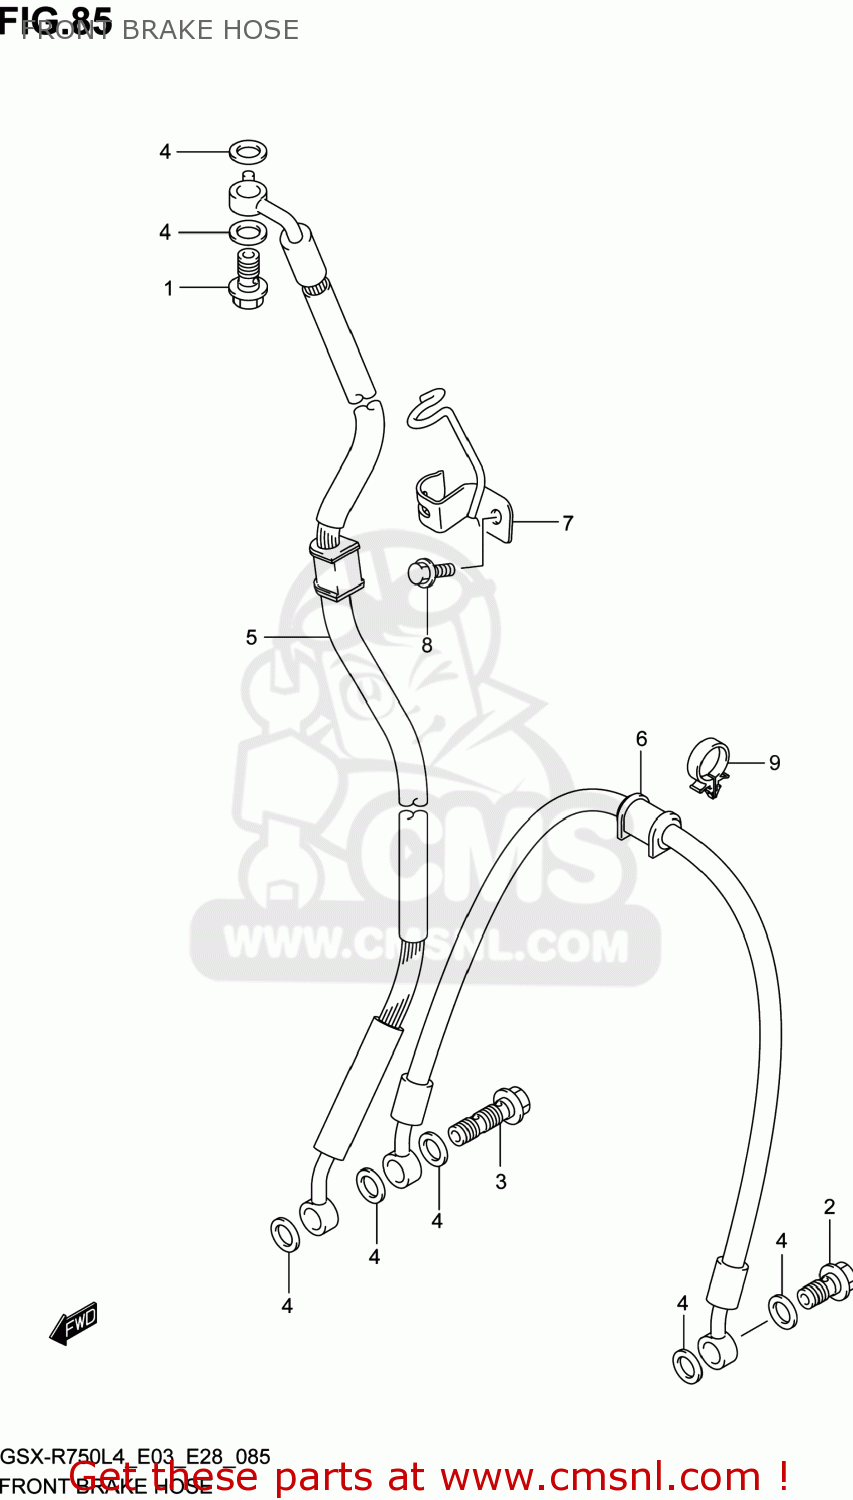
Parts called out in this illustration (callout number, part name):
1	BOLT UNION
2	BOLT UNION
3	BOLT UNION
4	WASHER(10X15X1.5)
5	HOSE,FR BRAKE NO.1
6	HOSE,FR BRAKE NO.2
7	CLAMP,FR BRAKE HOSE NO.1
8	BOLT
9	CLAMP
